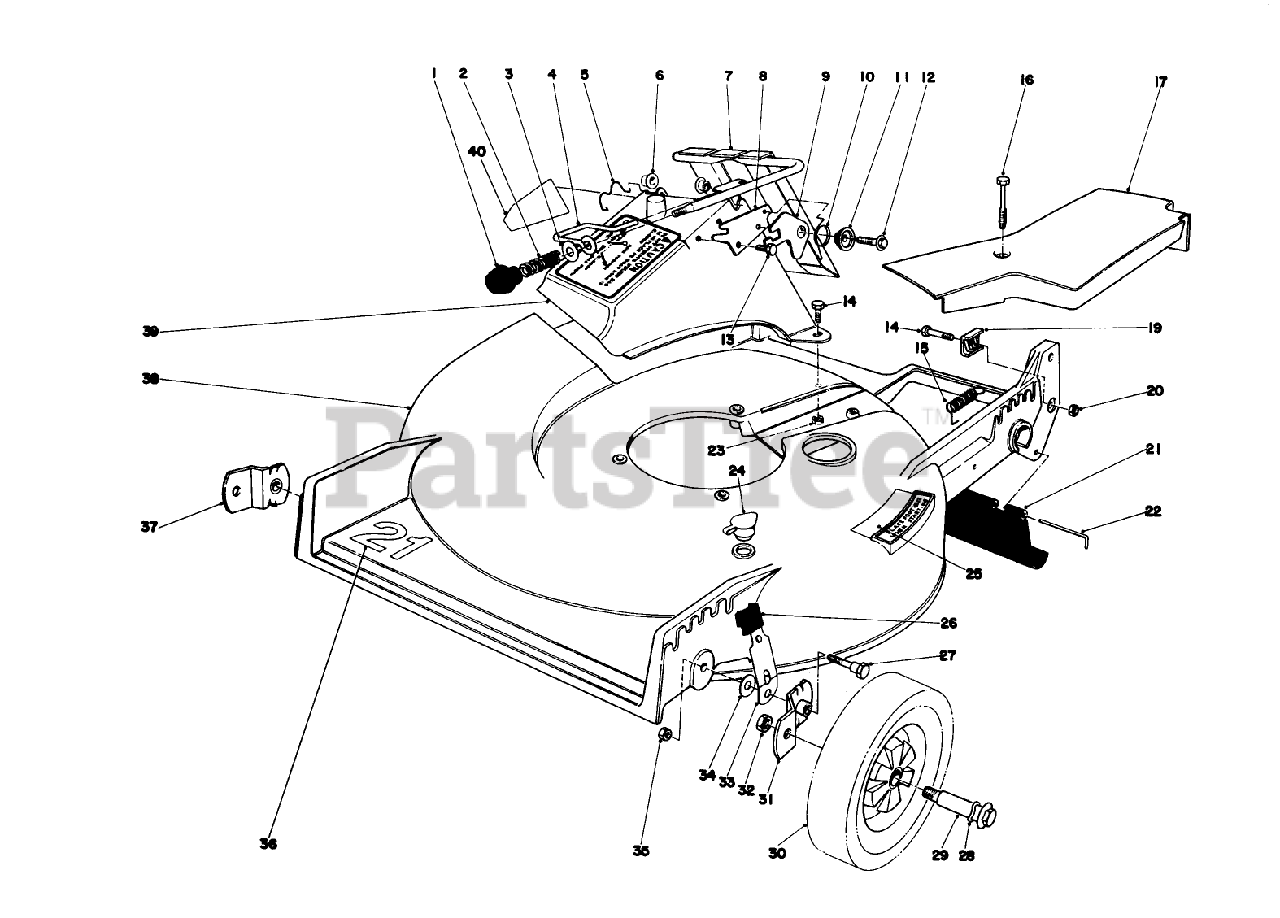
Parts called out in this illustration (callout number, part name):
2	COMPRESSION SPRING
3	WASHER
4	DOOR LATCH
5	DOOR RETAINER
6	BUSHING-NYLON
8	DOOR LATCH PLATE
10	TORSION SPRING
13	SCREW-HWH
14	SCREW-HH
15	IDLER SPRING
16	SCREW-HWH
19	CLAMP-CABLE
20	NUT-JAM
21	SHIELD - TRAILING
23	NUT-LOCK, NI
24	WASHOUT PLUG
26	KNOB-ARM
27	PIVOT SCREW
28	SPRING WASHER
29	BOLT-WHEEL
30	WHEEL TIRE ASM 8 IN
31	PIVOT ARM ASM A
34	WASHER-PIVOT
37	PIVOT ARM ASM
39	DISCHARGE CHUTE *B
